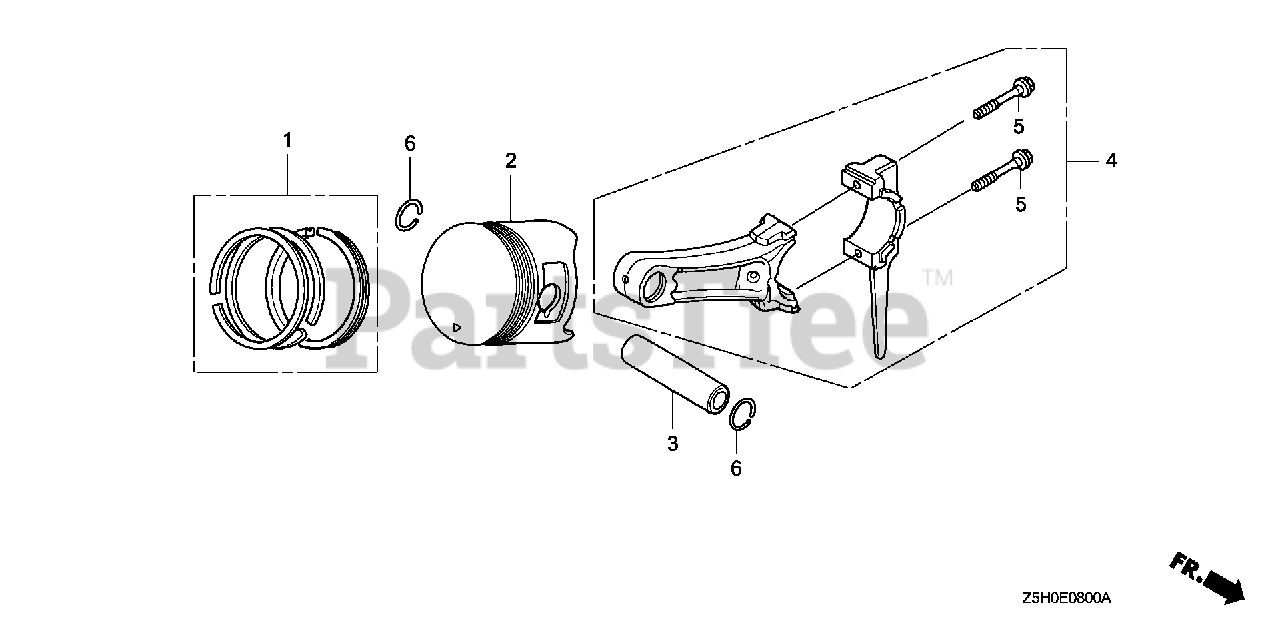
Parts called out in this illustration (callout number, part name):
1	RING SET, PISTON (STD) (NIPPON)
1	RING SET, PISTON (STD) (TPR)
1	RING SET, PISTON (0.25) (NIPPON)
1	RING SET, PISTON (0.25) (TPR)
1	RING SET, PISTON (0.50) (NIPPON)
1	RING SET, PISTON (0.50) (TPR)
1	RING SET, PISTON (0.75) (NIPPON)
1	RING SET, PISTON (0.75) (TEIKOKU)
1	RING SET, PISTON (0.75) (TPR)
2	PISTON (STD)
2	PISTON (0.25)
2	PISTON (0.50)
2	PISTON (0.75)
3	PIN, PISTON
4	ROD ASSY., CONNECTING (0.25 LOWER SIZE)
4	ROD ASSY., CONNECTING (STD)
5	BOLT, CONNECTING ROD
6	CLIP, PISTON PIN (18MM)
